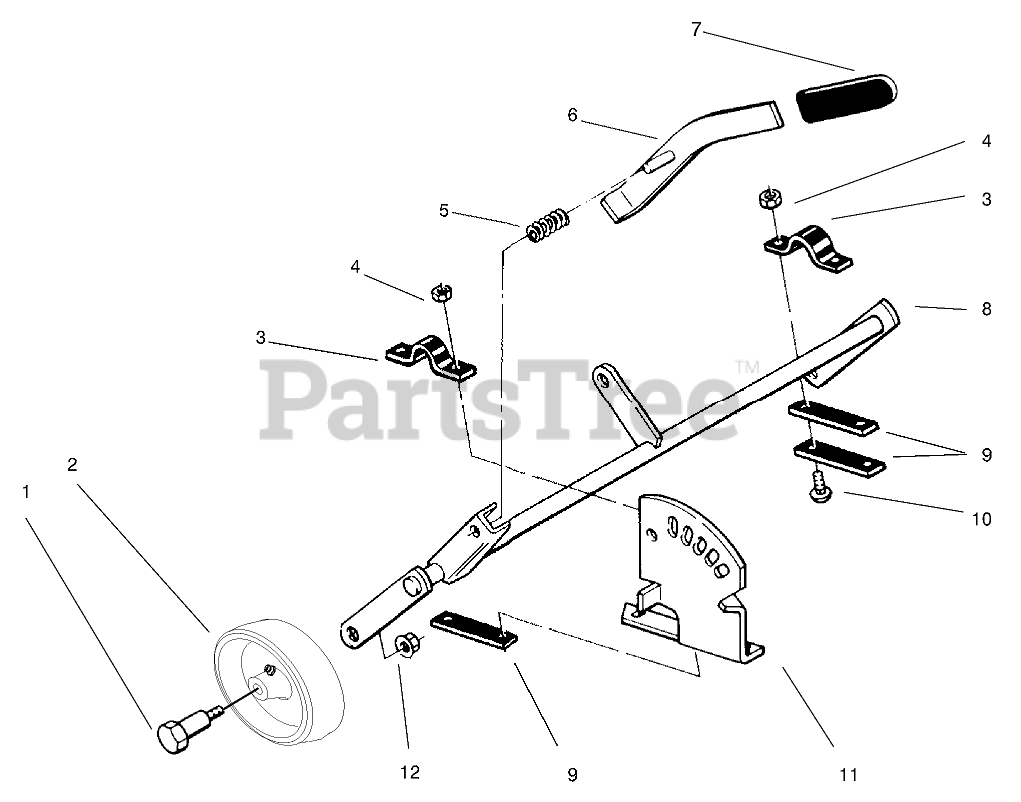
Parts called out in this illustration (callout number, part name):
1	BOLT-SHOULDER
2	WHEEL
3	CLAMP (BLACK)
4	NUT-LOCK, NI
5	SPRING-COMPRESSION
6	WA LEVER (RED)
8	WA GAGE WHL (RED)
9	STRAP 3/16 (BLACK)
10	BOLT-CARR
11	Quadrant
12	NUT-HEX
